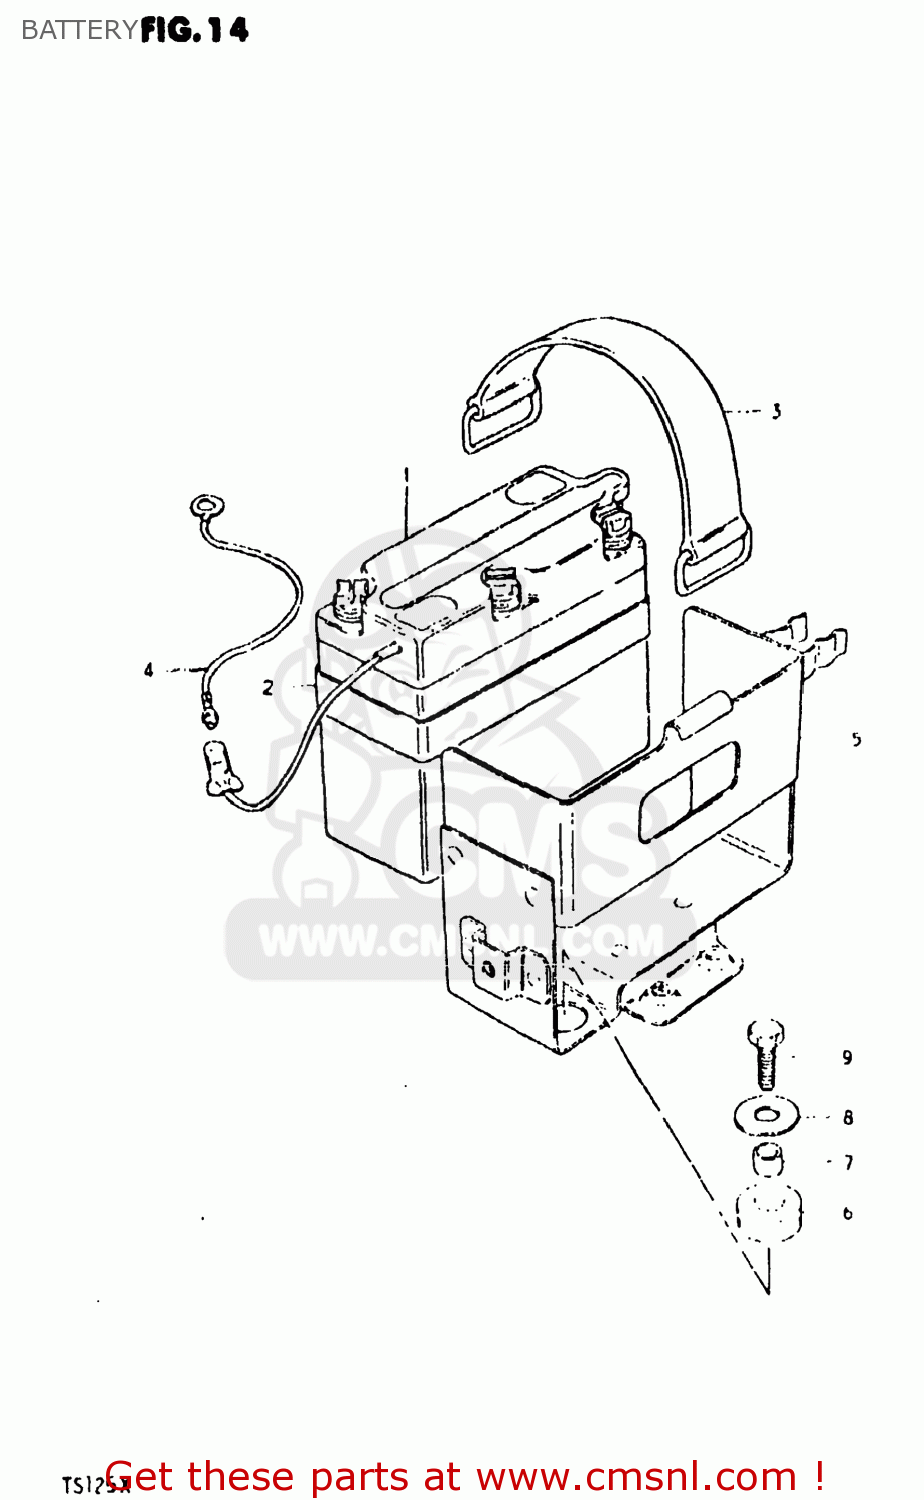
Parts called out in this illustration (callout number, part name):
1	BATTERY(6N4B-2A,6V4.2AH)
2	PROTECTOR,BATTERY
3	BAND
4	LEAD WIRE
5	HOLDER,BATTERY
6	CUSHION
7	SPACER (7X9X7)
8	WASHER (6.5X20X1.2)
9	BOLT, UPPER
